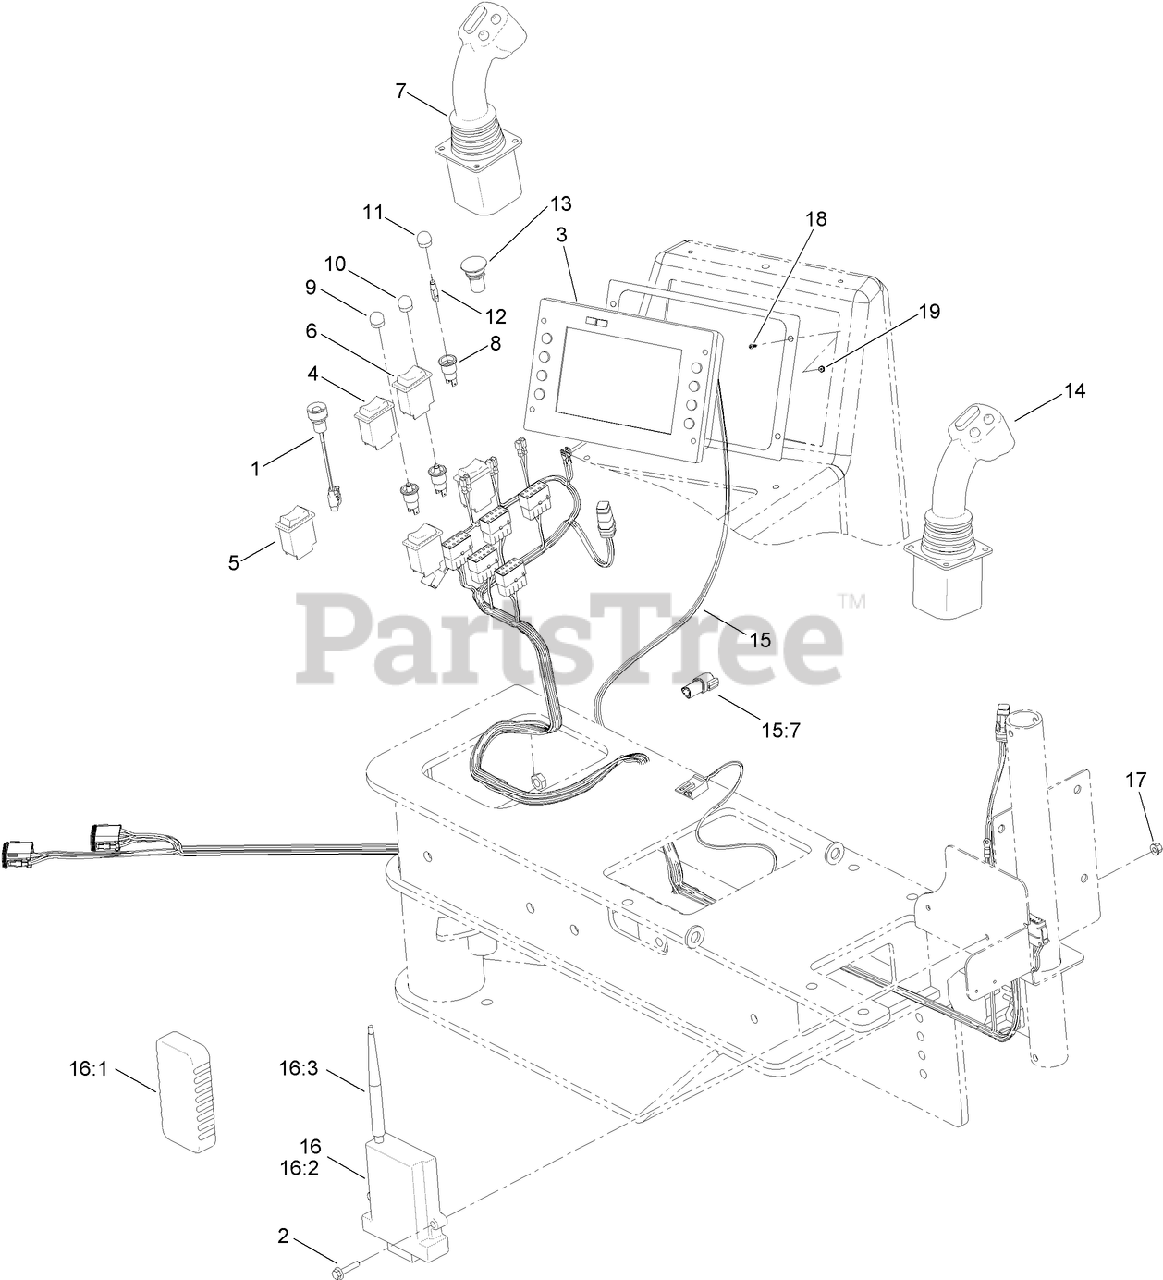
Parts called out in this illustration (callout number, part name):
1	SWITCH-START, GREEN BUTTON
2	SCREW-HHF
3	DISPLAY-DP600, UNPROGRAMMED
4	SWITCH-ROCKER, 2 POLE (ON/OFF)
5	SWITCH-ROCKER, 2 POLE
6	SWITCH-ROCKER, 1 POLE (ON)OFF/ON(OFF)
7	JOYSTICK-MODIFIED (LEFT HAND)
8	TYPE T-2 SOCKET ASM
9	LENS-DOME, FLUTED RED (TYPE T-2)
10	LENS-DOME, FLUTED GREEN (TYPE T2)
11	LENS-DOME, FLUTED AMBER (TYPE T2)
12	LAMP-LED
13	BUTTON-PUSH, RED MUSHROOM
14	JOYSTICK-CARRIAGE
15	HARNESS-WIRE, OPERATOR
15:7	RESISTOR-120 OHM
16	LONG RANGE EXIT SIDE LOCKOUT KIT
16:1	HANDHELD-LOCKOUT
16:2	BASE UNIT-LOCKOUT
16:3	ANTENNA-LOCKOUT
17	NUT-FLANGE, NI
18	SCREW-PRH, SLOTTED
19	NUT-LOCK, NI
